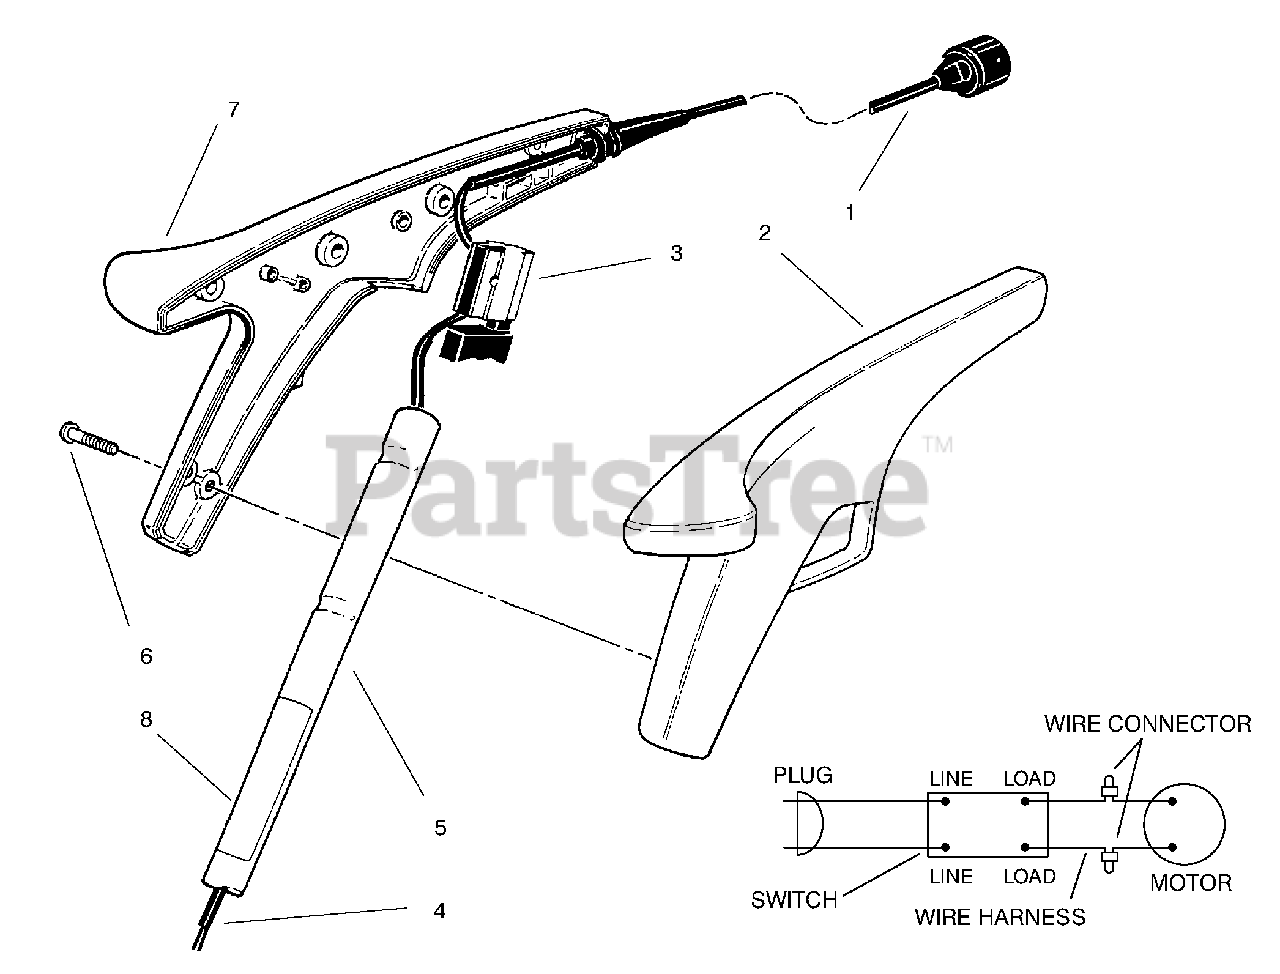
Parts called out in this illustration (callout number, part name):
1	Cord-Power
2	Grip-L.H.
4	Harness-Wiring
5	Tube Assy. (Incl. Ref.# 8)
7	Grip-R.H.
8	Decal-Safety
